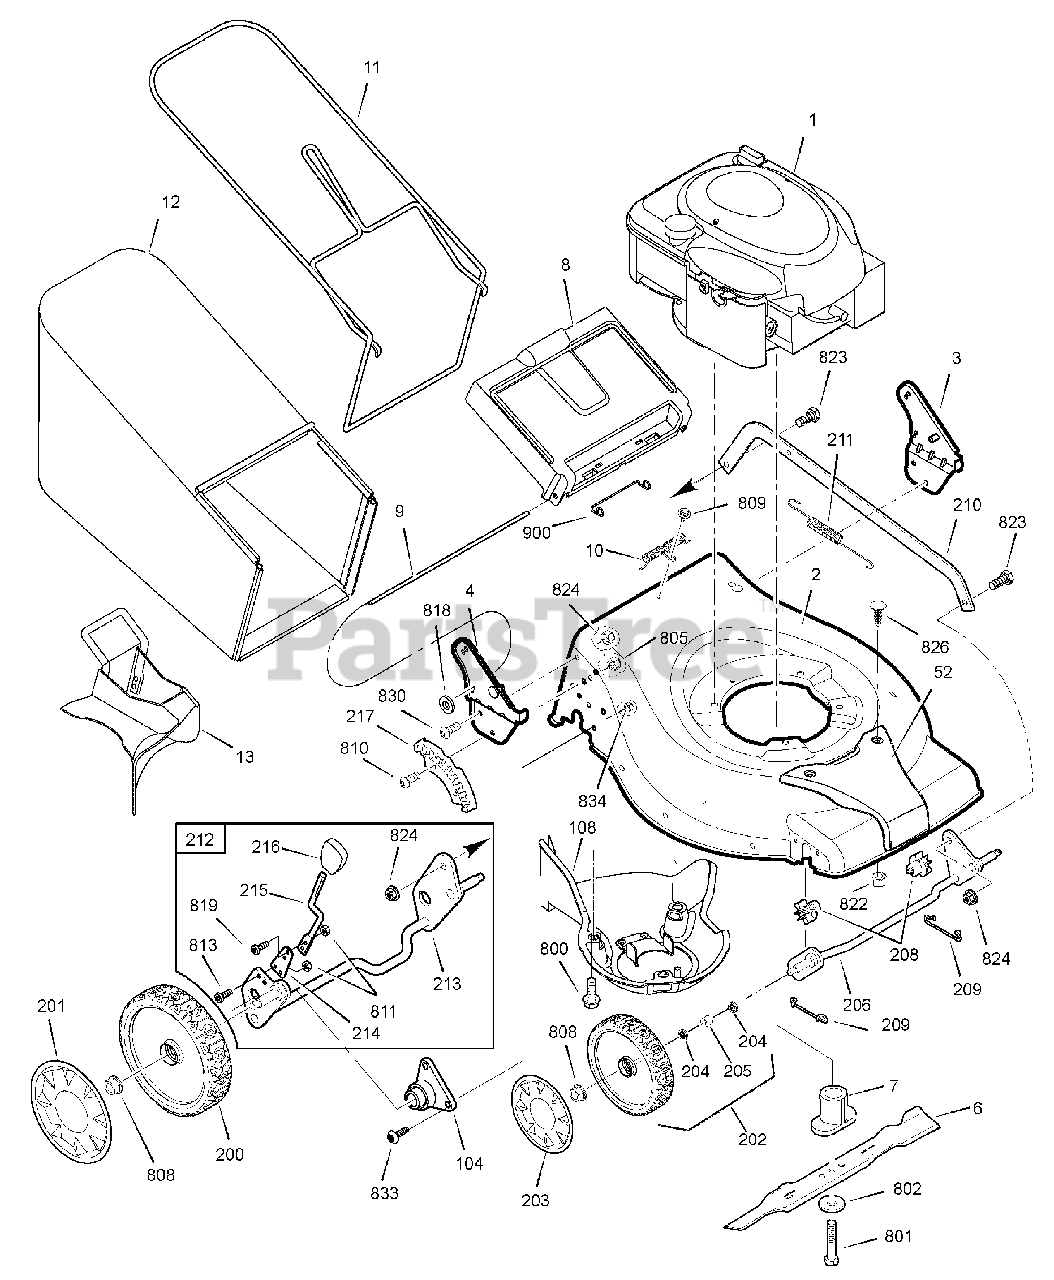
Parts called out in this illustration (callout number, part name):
1	* ENGINE, B&S 550 Series EU
2	MOWER HOUSING
3	BRACKET ASSEMBLY, Left Handle
4	BRACKET ASSEMBLY, Right Handle
6	BLADE, 16"
7	BLADE ADAPTER ASSEMBLY
8	DOOR, Rear
9	ROD, Rear Door
10	SPRING, Torsion Rear Door
11	FRAME ASSEMBLY
12	BAG ASSEMBLY
13	MULCH PLUG
52	HOUSING COVER, Front
104	SLEEVE ASSEMBLY, Rear Axle
108	BELT COVER ASSEMBLY
200	WHEEL, Rear
201	HUBCAP, Rear
202	WHEEL, Front, Complete
203	HUBCAP, Front
204	WHEEL BEARING (Not Available)
205	SPACER (Not Available)
206	CROSSBAR ASSEMBLY, Front
208	BUSHING, Front Crossbar
209	SPRING, Clip Crossbar
210	LINK, Single Lever
211	SPRING, Extension
212	CROSSBAR ASSEMBLY, Rear (Not Available)
213	REAR CROSSBAR
214	SPRING, Adjuster
215	LEVER, Height Adjustment
216	KNOB, Adjuster
217	BRACKET, Height Adjuster
800	SCREW, Hex Head, 3/8-16 x 1
801	BOLT, Blade, 3/8-24 x 2
802	WASHER, Belleville
805	NUT, Nylock, M8 x 1-1/4
808	NUT, Flange, 3/8-16
809	SCREW, Self Tap, #10-16 x 1/2
810	BOLT, Hex Key Head
811	NUT, Nylock
813	SCREW, Torx Head, M5 x .8 x 14mm
818	NUT, Speed
819	SCREW, Torx Head, M5 x .8 x 12.5mm
822	NUT, Hex, 1/4-20
823	BOLT, Shoulder, 5/16-18 x 1
824	Nut, Flange, 5/16-18
826	SCREW, Truss Head Torx, 1/4-20 x 7/8
830	SCREW , 5/16-18 x 3/4
833	SCREW, Torx, 1/4-20 x 5/8
834	NUT, Flange Lock, 1/4-20
900	SPRING CLIP, Rear Door
